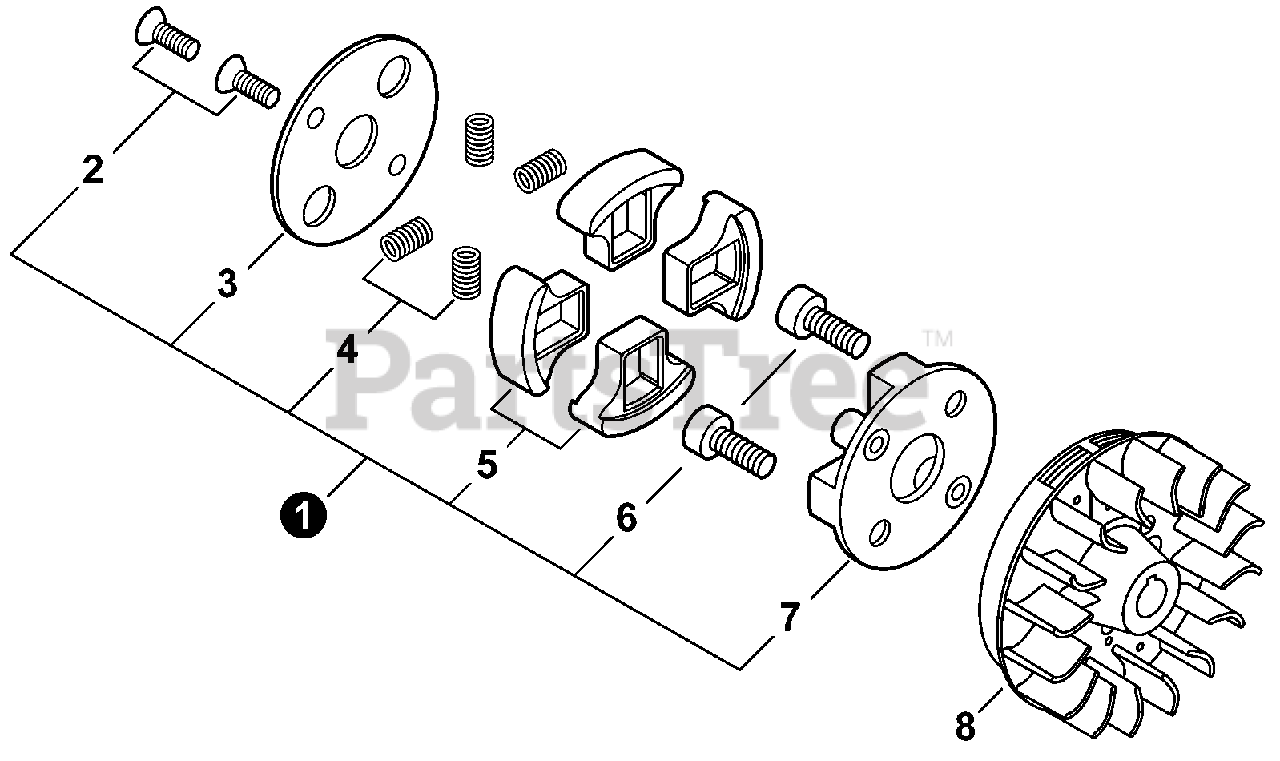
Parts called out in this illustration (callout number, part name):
1	CLUTCH ASSY
2	BOLT 5
3	PLATE, CLUTCH
4	SPRING, CLUTCH
5	SHOE, CLUTCH
6	BOLT, CLUTCH
7	BOSS, CLUTCH
8	FLYWHEEL
